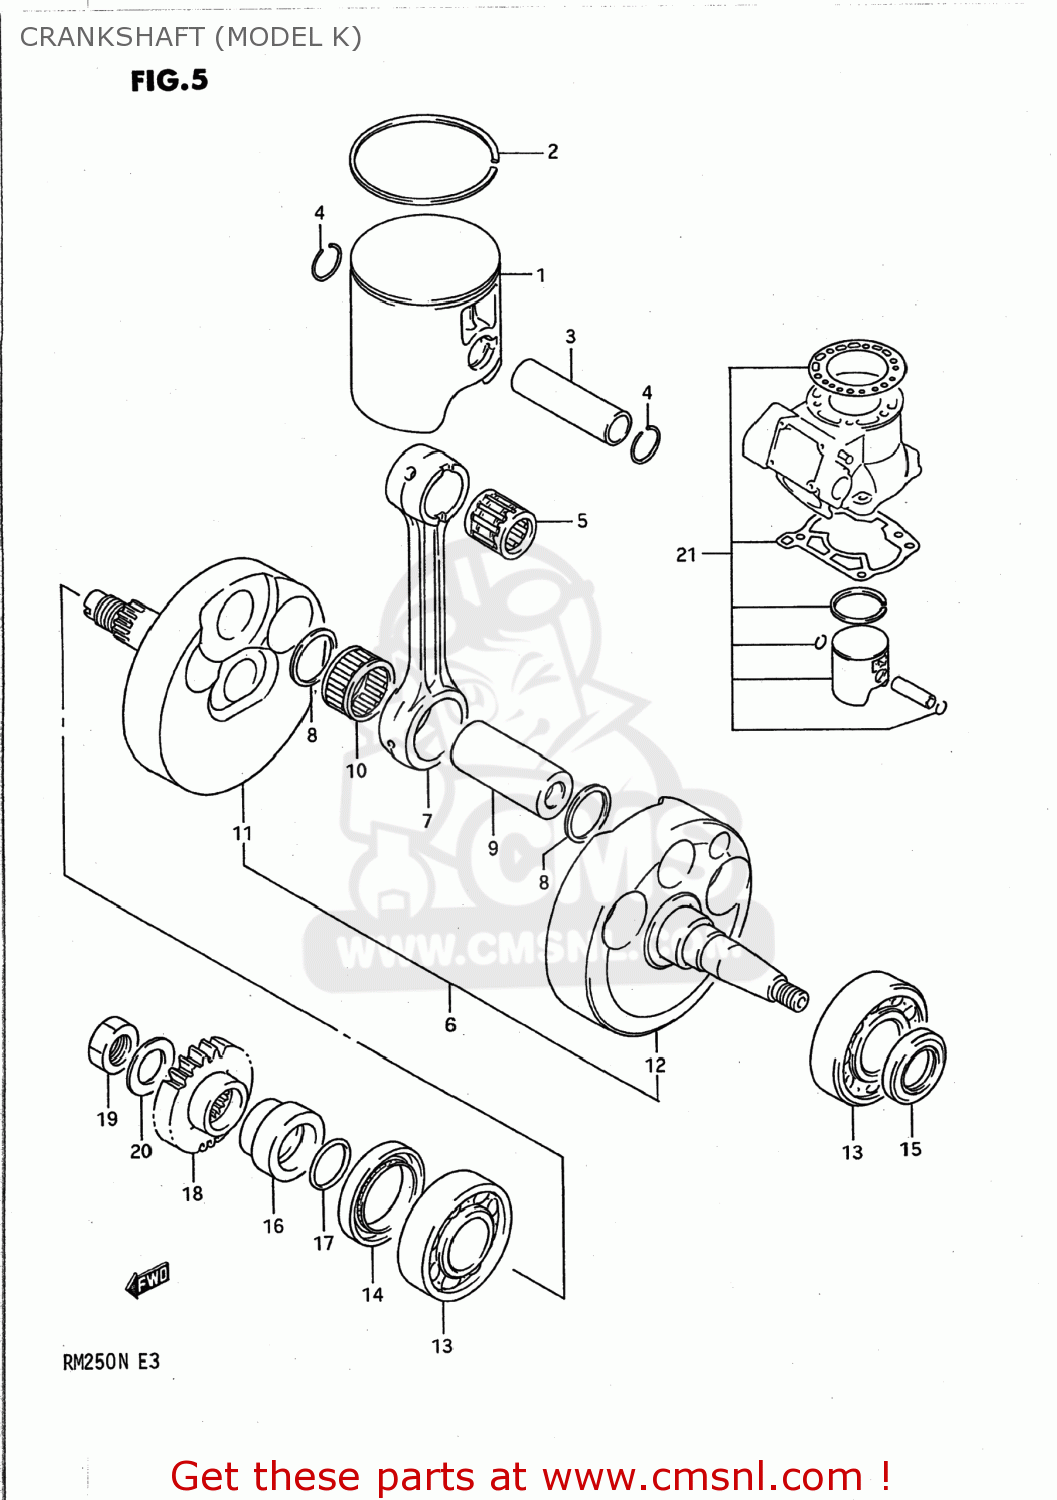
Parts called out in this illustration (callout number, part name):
1	PISTON
2	RING,PISTON
3	PIN,PISTON
4	CIRCLIP
5	BEARING(18X23X22)
6	CRANKSHAFT ASSEMBLY
7	CONNECTION ROD
8	WASHER(24X29X1.5)
9	PIN COMP,CRANK
10	BEARING
11	CRANKSHAFT,R
12	CRANKSHAFT,LEFT
13	BEARING(25X62X17)
14	OIL SEAL
15	OIL SEAL
16	SPACER,PRIMARY DRIVE GEAR
17	O RING(D:2.4,ID:21.8)
18	GEAR,PRIMARY DRIVE
19	NUT
20	WASHER
21	TOP END KIT,ENGINE
